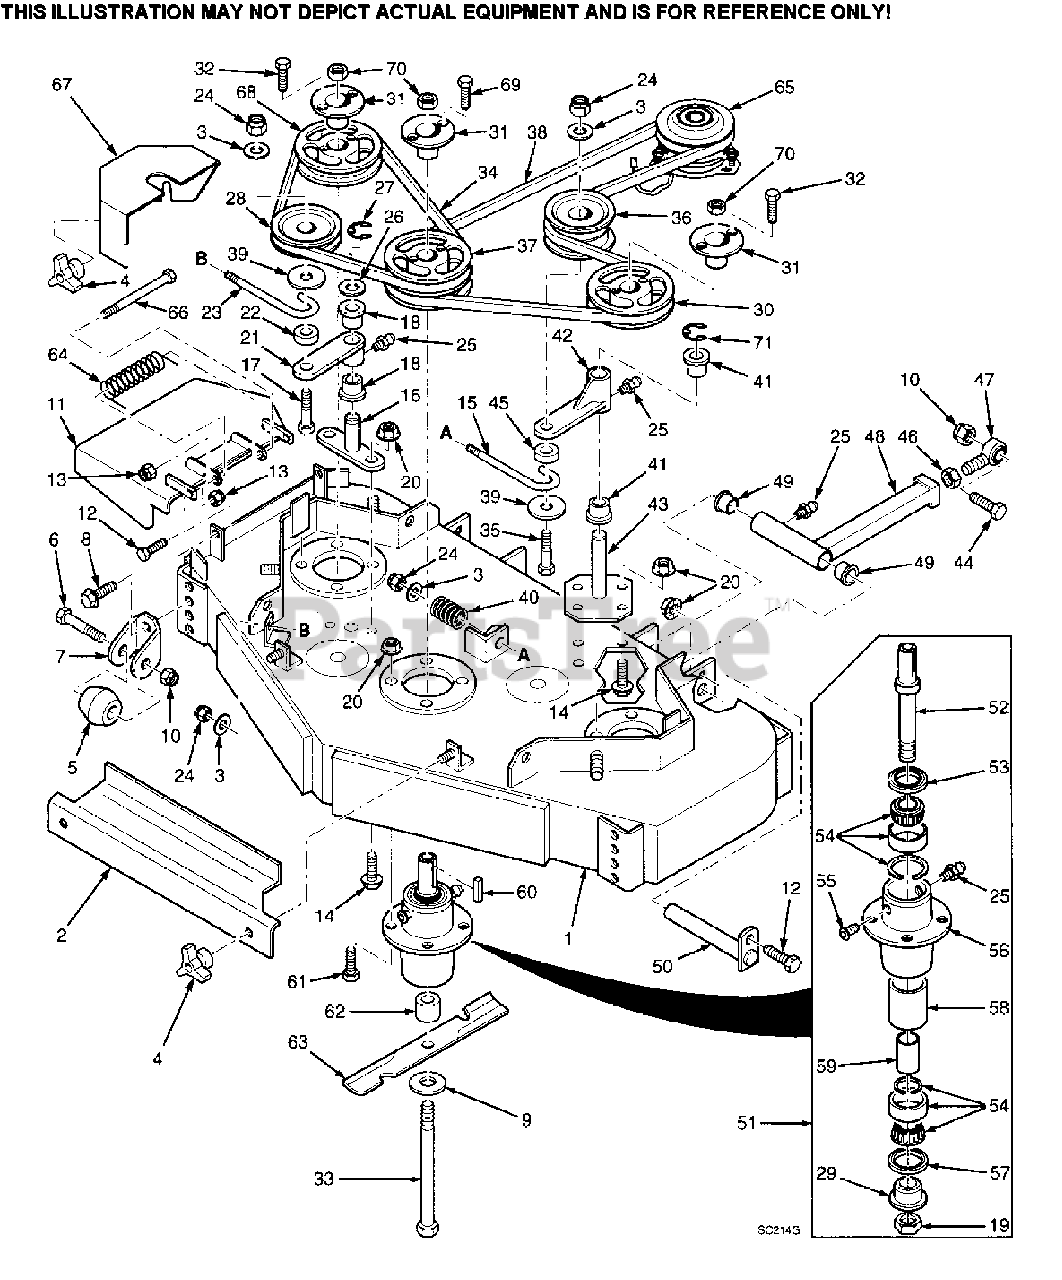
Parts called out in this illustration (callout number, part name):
1	CUTTER DECK(INCLUDES DECALS)
2	BELT COVER, FRONT
3	FLATWASHER, 3/8" SPECIAL(.391 X .938 X .105)
4	WING NUT, 3/8-16
5	ANTI-SCALP WHEEL
6	BOLT, HEX HEAD 5/8-11 X 4-1/2"
7	ANTI-SCALP WHEEL BRACKET
8	BOLT, HEX SERRATED FLANGE 3/8-16 X 1"
9	FLATWASHER, 5/8"(.688 X 1.75 X .134)
10	NUT, HEX ELASTIC STOP 5/8-11
11	DISCHARGE CHUTE
12	BOLT, HEX HEAD 5/16-18 X 1"
13	NUT, HEX ELASTIC STOP 5/16-18
14	BOLT, HEX SERRATED FLANGE 5/16-18 X 3/4"
15	"J" ROD
16	IDLER PIVOT BASE
17	BOLT, HEX HEAD 3/8-16 X 2-1/4"
18	BUSHING
19	NUT, SPECIAL 1-1/16-18
20	NUT, HEX SERRATED FLANGE 5/16-18
21	IDLER ARM(INCLUDES BUSHINGS & GREASE
22	SPACER
23	"J" ROD
24	NUT, HEX ELASTIC STOP 3/8-16
25	GREASE FITTING
26	FLATWASHER, 3/4"
26	FLATWASHER, 3/4" SPECIAL
27	RING, RETAINING 3/4" EXTERNAL "E"
28	PULLEY, IDLER
29	SPINDLE BUSHING, BOTTOM
30	PULLEY, LH SPINDLE
31	TAPERED HUB, 1-1/8 BORE
32	BOLT, HEX HEAD 1/4-20 X 3/4"
33	BOLT, HEX HEAD 5/8-11 X 9-1/2"
34	BELT, RH BLADE DRIVE
35	BOLT, HEX HEAD 3/8-16 X 4-1/2"
36	PULLEY, IDLER CUTTER ENGAGEMENT
37	PULLEY, DOUBLE GROOVE
38	BELT, BLADE DRIVE
39	FLATWASHER, 3/8"(.375 X 1.5 X .06)
40	SPRING, IDLER TENSION
41	BUSHING
42	IDLER ARM(INCLUDES BUSHINGS & GREASE
43	IDLER PIVOT BASE
44	BOLT, HEX HEAD 5/8-11 X 3"
46	NUT, HEX 5/8-18 UNF
47	ROD END
48	PUSH ARM(INCLUDES 25, 46, 47, AND 49)
49	BUSHING
50	PUSH ARM SHAFT
51	SPINDLE ASSEMBLY
52	SPINDLE SHAFT
53	SEAL, TOP
54	BEARING ASSEMBLY(1 REQUIRED PER SPINDLE)
55	RELIEF FITTING, TAPERED SPINDLE
56	SPINDLE HOUSING
57	SEAL, BOTTOM
58	SPACER, OUTSIDE
59	SPACER, INSIDE
60	KEY, 1/4 X 1/4 X 2"
61	BOLT, HEX HEAD 5/16-18 X 1-1/4"
62	SPACER, TAPERED SPINDLE
63	CUTTER BLADE, 16-1/2" STANDARD
63	CUTTER BLADE, 16-1/2" HIGH LIFT
64	SPRING, DISCHARGE CHUTE
65	ELECTRIC CLUTCH
66	BOLT, HEX HEAD 5/16-18 X 4.25"
67	BELT COVER, LH
67	BELT COVER, RH
68	PULLEY, RH SPINDLE
69	BOLT, HEX HEAD 1/4-20 X 1.375 FULL THREAD
70	NUT, HEX 5/8-11 UNC
71	RING, RETAINING 1-1/8" EXTERNAL "E"
